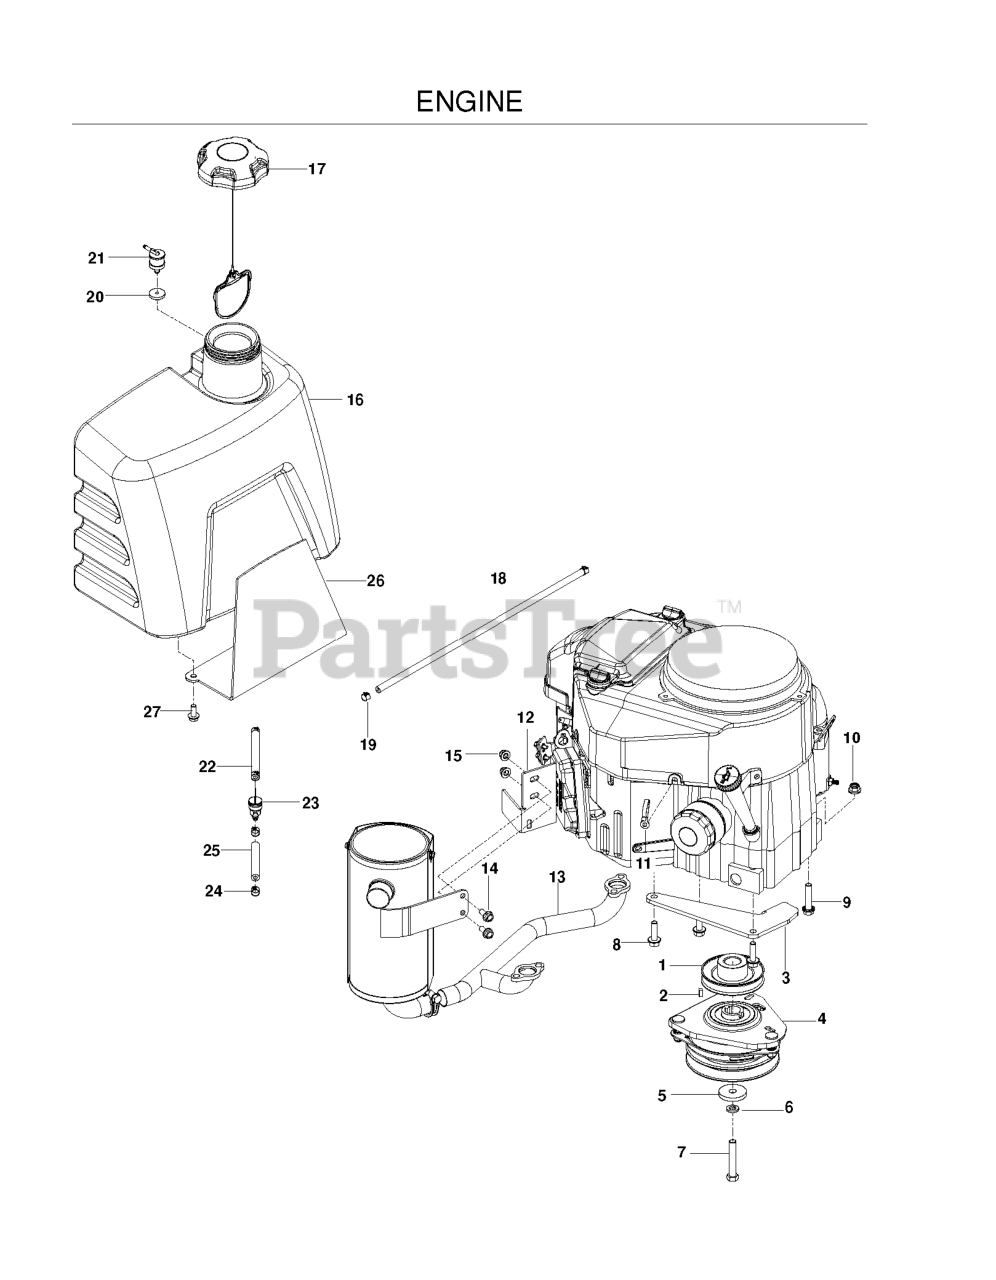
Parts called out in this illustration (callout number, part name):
1	PULLEY - ENGINE
2	SQUARE KEY - 1/4 X .5
3	CLUTCH STOP
4	CLUTCH.ELECTRIC.LT.48"*
5	SPINDLE WASHER
6	WASHER 7/16 LOCK
7	BOLT 7/16F X 2 1/2
8	HHFS 3/8-16 X 1.25 GD 5
9	BLT 3/8-16X1-3/4 WHIZLK ZN SP
10	NUT 3/8-16 HEX FLG NYLOC ZD
12	SUPPORT, MUFFLER
13	MANIFOLD, EXHAUST
14	HHFS 5/16-18 X 3/4
15	5/16-18 NYLOC FLANGE NUT
16	TANK, FUEL BLK
17	CAP, FUEL
18	HOSE, 3/16" VAPOR, 52"
19	CLAMP, HOSE
20	GROMMET, CHECK VALVE
21	VALVE.FUEL.CHECK
22	FUEL LINE 5"
23	FUEL VALVE
24	HOSE CLAMP
25	FUEL HOSE 3.5
26	PLATE ID, ORANGE
27	HHFS 5/16-18 X 3/4
